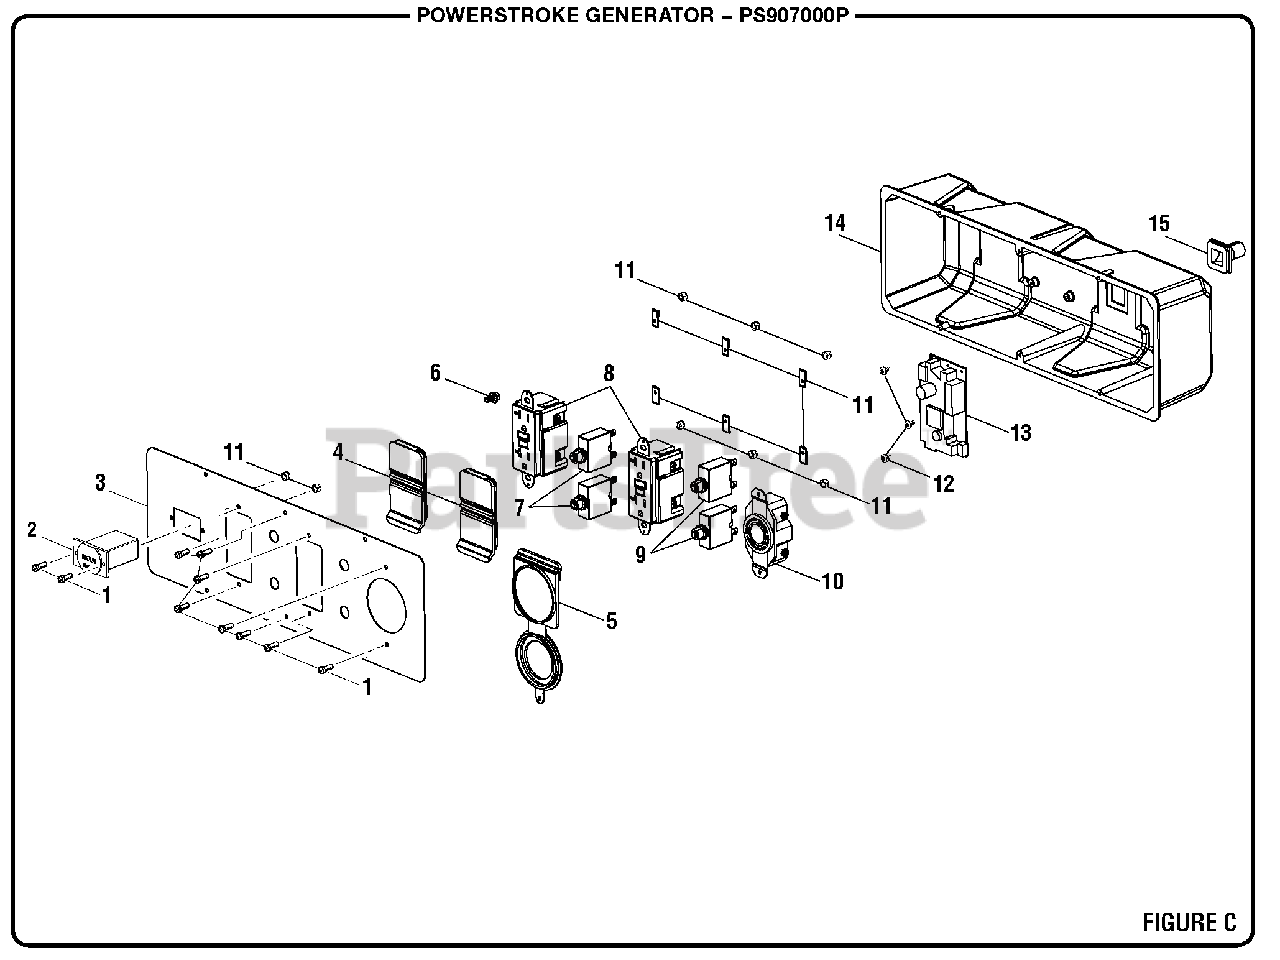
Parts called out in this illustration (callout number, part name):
1	Screw (6-20 x 3/8 in., Pan Hd.)
2	Hour Meter
3	Front Panel
4	120 Volt Outlet Covers
5	240 Volt Outlet Covers
6	Bolt (M5 x 10 mm, Hex Flange Hd.)
7	Circuit Breaker (30 Amp)
8	120 Volt Duplex GFCI Receptacle
9	Circuit Breaker (20 Amp, 125 Volt)
10	Twist Lock Receptacle (120/240 Volt, 30 Amp, L14-30R)
11	U- Clip Nut (#6)
12	Screw (M3 x 5 mm, Pan Hd.)
13	Battery Charger
14	Control Box (Back Panel)
15	Rubber Boot (Control Panel Assembly)
